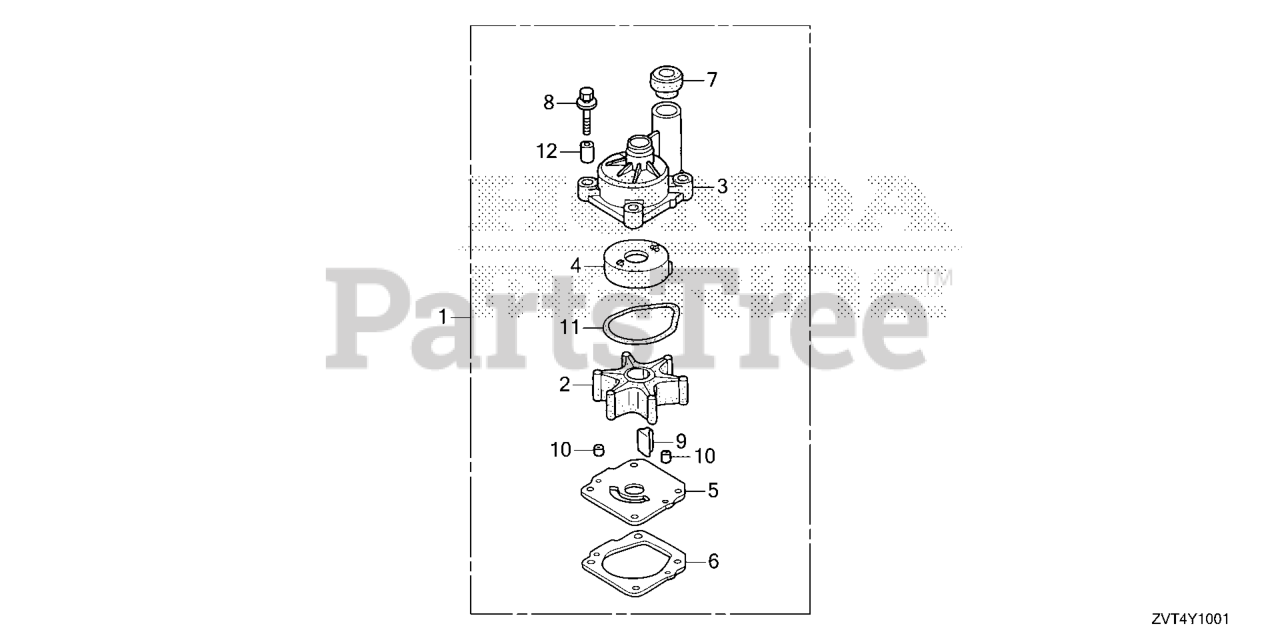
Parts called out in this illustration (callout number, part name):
1	PUMP KIT, IMPELLER
2	IMPELLER, PUMP
3	HOUSING, IMPELLER
4	LINER, PUMP
5	COVER, IMPELLER
6	GASKET B, IMPELLER
7	RING, WATER TUBE SEAL
8	BOLT-WASHER (8X40)
9	KEY, WOODRUFF
10	PIN, DOWEL (6X10)
11	O-RING, WATER PUMP
12	COLLAR, DISTANCE
